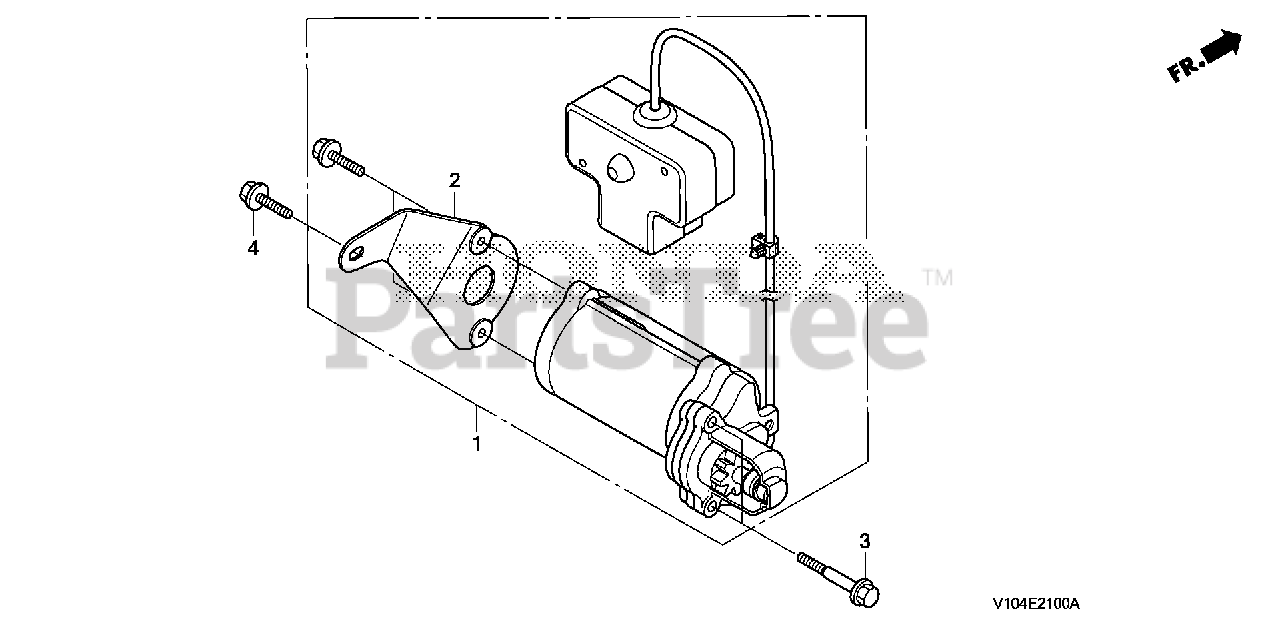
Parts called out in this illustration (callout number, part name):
1	STARTER MOTOR ASSY. (AC)
3	BOLT, SPECIAL (6MM)
4	BOLT, FLANGE (6X14) (CT200)
